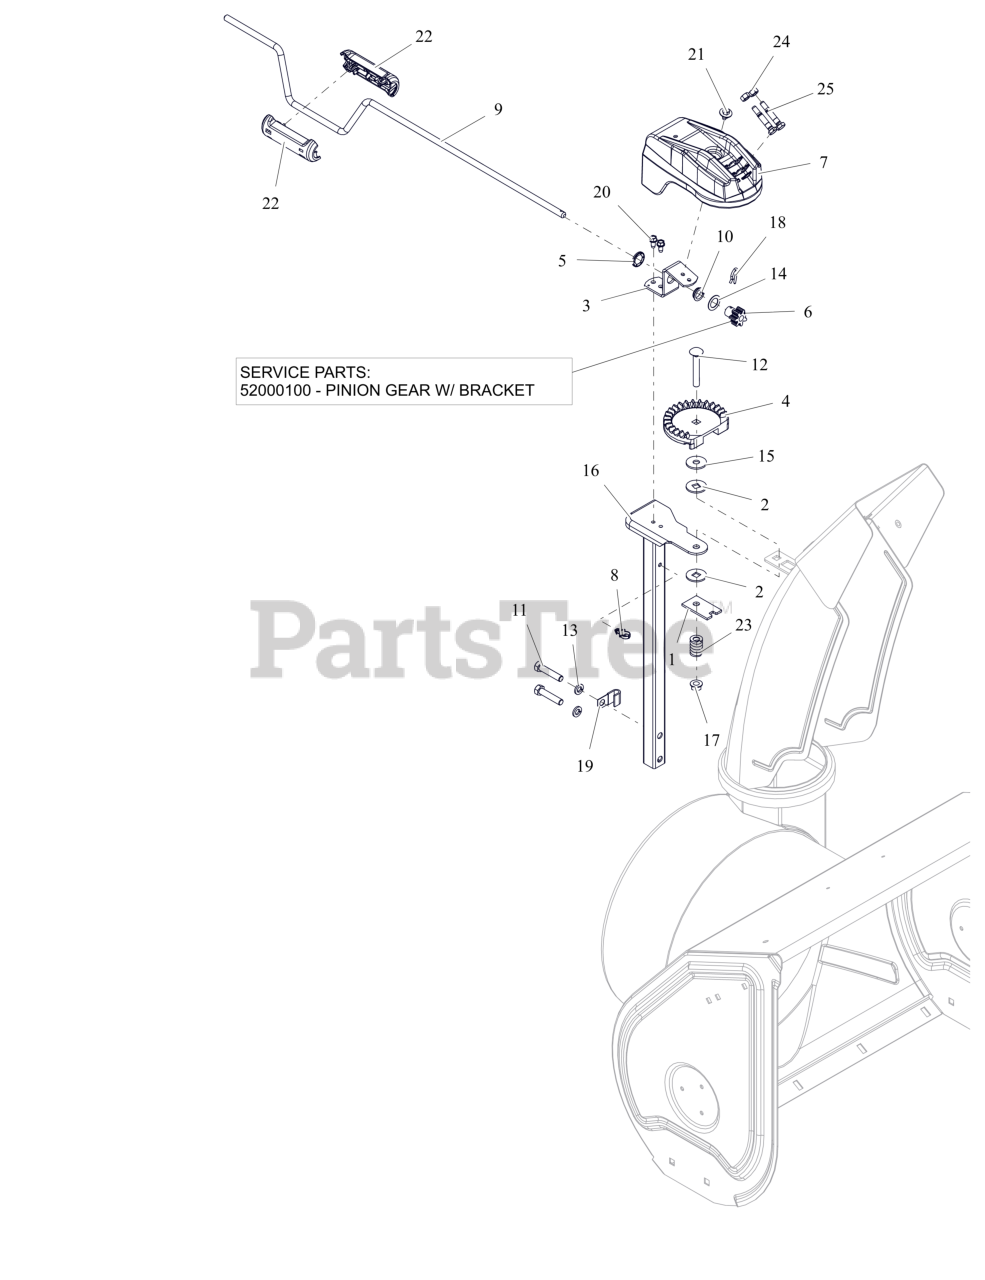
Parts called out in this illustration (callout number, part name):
1	PLATE, FRICTION
2	FRICTION WASHER
3	BRACKET, PINION GEAR
4	CHUTE GEAR
5	PUSHNUT .625
6	PINION GEAR - CHUTE
6	PINION GEAR W/BRACKET
7	COVER, MOUNT - ICE DRILL
8	CLIP, CABLE GUIDE
9	ROD, CHUTE CRANK
10	BUSHING, POLYLINER-.63 SNAPIN
11	BLT, HEX .38-16X1.75 G5 ZCC
12	BLT,RHSN .38-16X2.50 G5 ZCC
13	WSHR,LK-REG .375X.094 ZCC
14	WSHR-THRST .625 X 1.0 X .03
15	WSHR FL STL .406X1.25X.10ZC120
16	PEDESTAL, CHUTE - CRANK
17	NUT-LK-CTR-FLG .375-16 GF ZCC
18	PIN, SPRING CLIP
19	J-CLAMP
20	SCR-TAP .25-20X.50 HWH ZCC
21	SCR, TAP .25-20X.50 LG HWH ZCC
22	KNOB- CHUTE CRANK
23	SG-COMP .187X.56X1.62
24	NUT,LK-CTR .31-18 GA ZCC
25	SHEAR BOLT SERVICE ASSEMBLY
